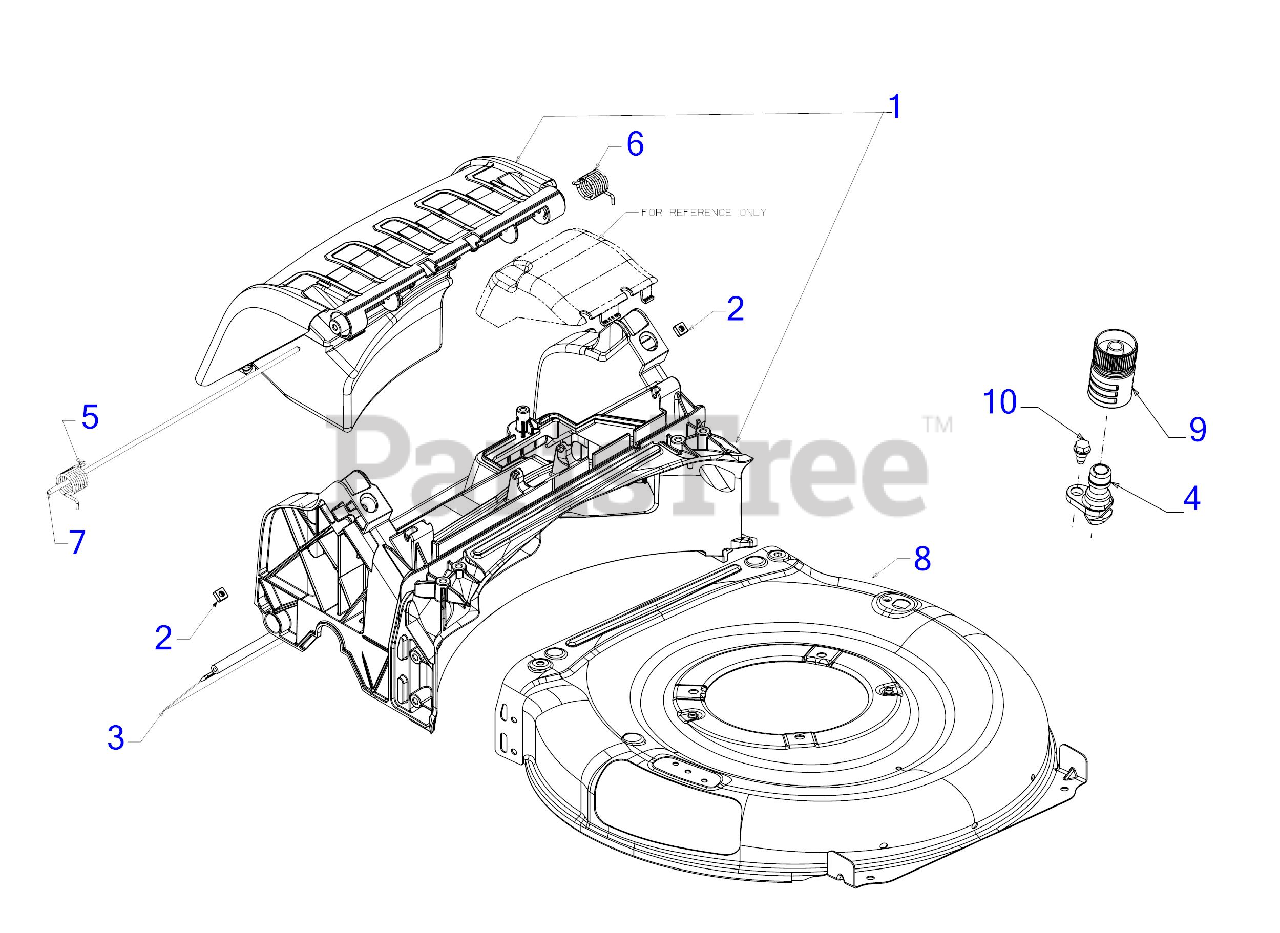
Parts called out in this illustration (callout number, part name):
1	REAR BAG BAFFLE ASSEMBLY
2	SQUARE NUT 1/4-20
3	TRAILSHIELD
4	DECK WASH NOZZLE
5	TORSION SPRING (RH)
6	TORSION SPRING (LH)
7	REAR DOOR PIVOT ROD
8	21" DECK (3N1)
9	WATER NOZZLE
10	SHOULDER SCREW 1/4-20 x .50
